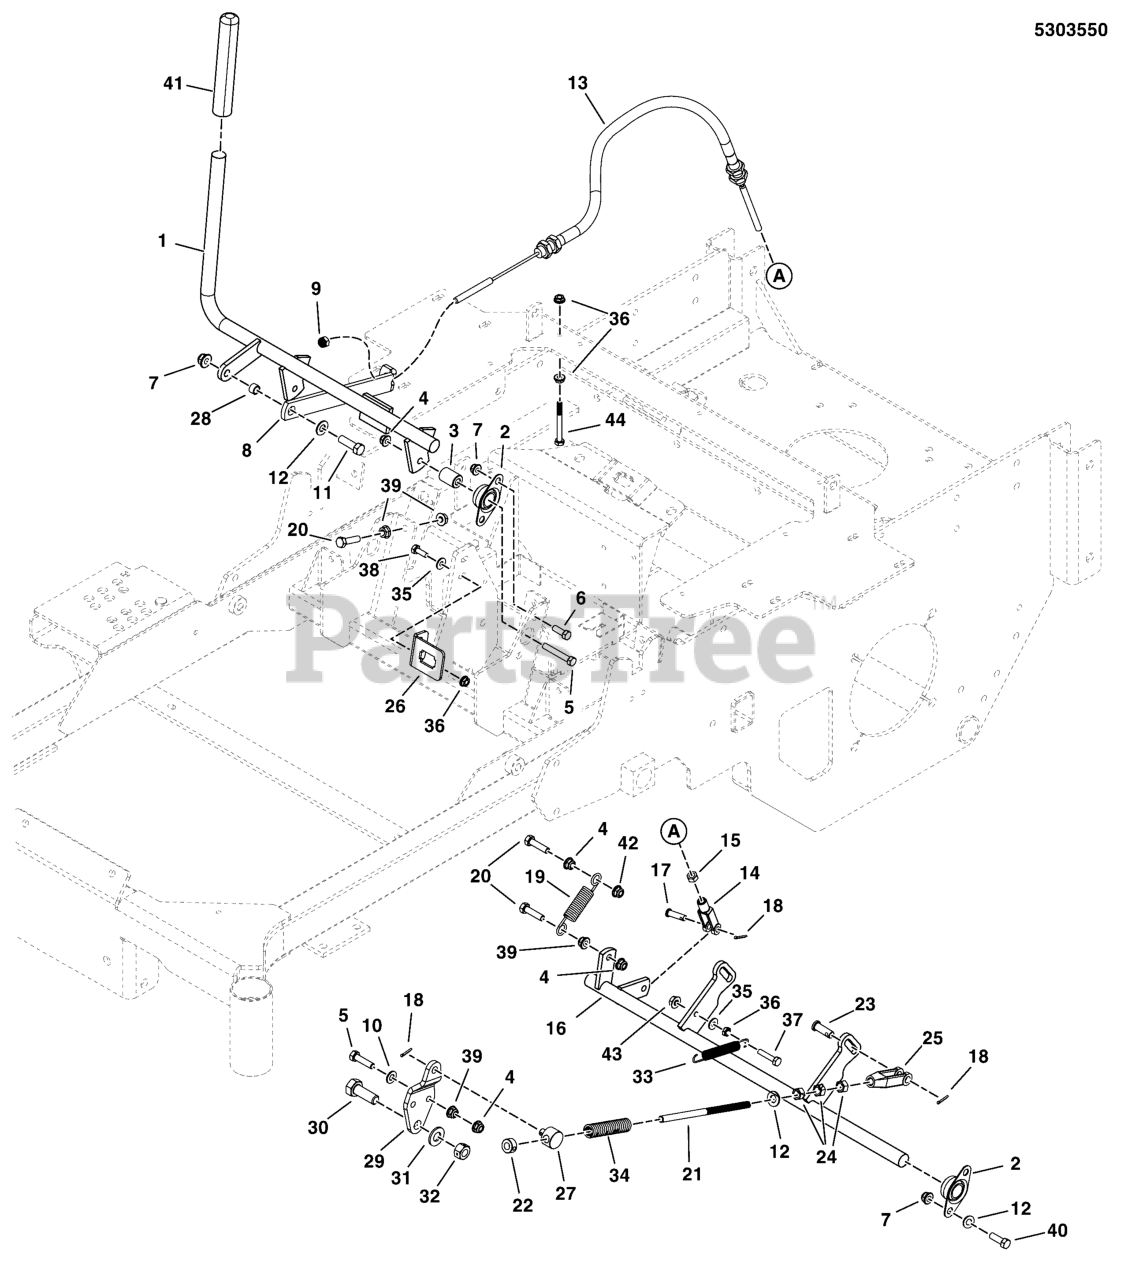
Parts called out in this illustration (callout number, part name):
1	WELD, BRAKE SHAFT - BLK
2	BEARING, BRONZE FLANGE, 3/4
3	SPACER, .32 X .75 X 1.06, PM
4	NUT, 5/16-18 HEX NYLOCK FLANGE
5	BOLT, 5/16-18 X 1-3/4 GD5 YZ
6	BOLT, 3/8-16 X 3/4" GD5 CZ
7	NUT, 3/8-16 HEX NYLOCK FLANGE
8	LINK, BRAKE LOCK - BLK
9	NUT, 5/16-24 HEX NYLON LOCK
10	WASHER, 5/16" SAE
11	BOLT, 3/8-16 X 1-1/4" GD5 CZ
12	WASHER, 3/8 SAE
13	CABLE, PARKING BRAKE IS2000
14	CLEVIS, 5/16-24, STEEL, CLEAR ZINC
15	NUT, 5/16-24 HEX
16	WELD, SHAFT, REAR BRAKE - BLK
17	PIN, CLEVIS, 5/16 X 1, PLATED
18	PIN, 3/32 X 0.750, COT, ZINC/CLEAR
19	SPRING, EXTENSION
20	BOLT, 5/16-18 X 1-1/4 GD5 YZ
21	ROD, BRAKE ADJUSTMENT, CZ
22	COLLAR, 3/8 SET
23	PIN, CLEVIS, 3/8 X 1-1/8, PLATED
24	NUT, 3/8-24 HEX JAM
25	CLEVIS, 3/8-24 RH, 3/8" PIN HOLE, CLR ZN
26	BRACKET, SWITCH MOUNT - BLK
27	ADJUSTER, BRAKE LINKAGE
28	SPACER, .38 X .50 X .31, CZ
29	PLATE, BRAKE ARM EXTENSION - BLK
30	BOLT, 1/2-13 X 1-1/2 GD5 CZ
31	WASHER, 1/2 SAE
32	NUT, 1/2-13 HEX SIDE LOCK
33	SPRING, EXTENTION, .50 OD X 4.12 FL
34	SPRING-COMP, .496ID X 3.00LG X .112WR
35	WASHER, 1/4 SAE
36	NUT, 1/4-20 HEX SERR. FLANGE
37	BOLT, 1/4-20 X 1-1/4, GD5
38	BOLT, 1/4-20 X 3/4 GD5 YZ
39	NUT, 5/16-18 HEX SERRATED FLANGE (SMALL)
40	BOLT, 3/8-16 X 1" GD5 CZ
41	GRIP, FOAM, 3/4 ID X 6 X .187
42	NUT, 5/16-18 HEX NYLON LOCK
43	NUT, 1/4-20 HEX NYLOCK FLANGE
44	BOLT, 5/16-18 X 3-3/4 GD5
